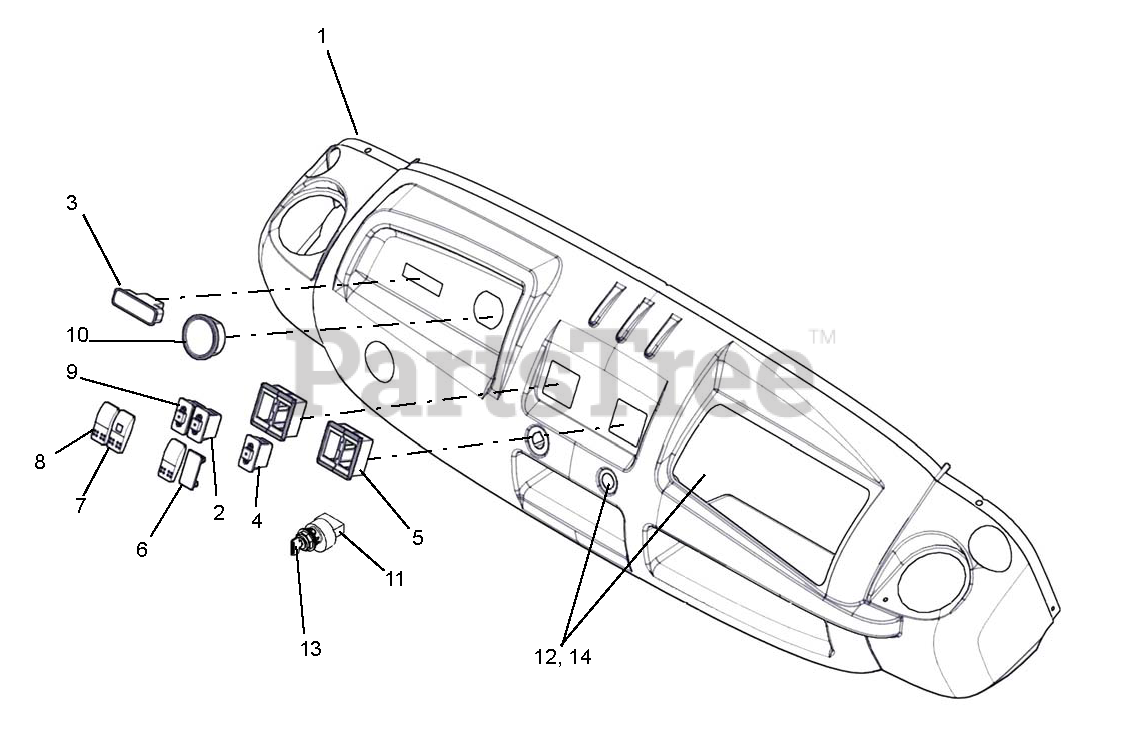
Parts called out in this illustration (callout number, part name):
1	ASSEMBLY,DASH/GLOVEBOX
2	SWITCH,4X4,LIGHTED
3	INDICATOR LAMP, 6 LENS
4	DUMP SWITCH WAYTEK 44304
5	SWITCH MOUNT END
6	PANEL PLUG
7	ACTUATOR,SWITCH,4X4
8	SWITCH ACTUATOR
9	SWITCH,HEADLIGHT
10	GAUGE, FUEL/HOUR METER
11	IGNITION SWITCH W/2 KEYS(6PIN)
12	POWER OUTLET, 12VOLT
13	KEY W/SHIELD
14	CAP, 12V OUTLET
